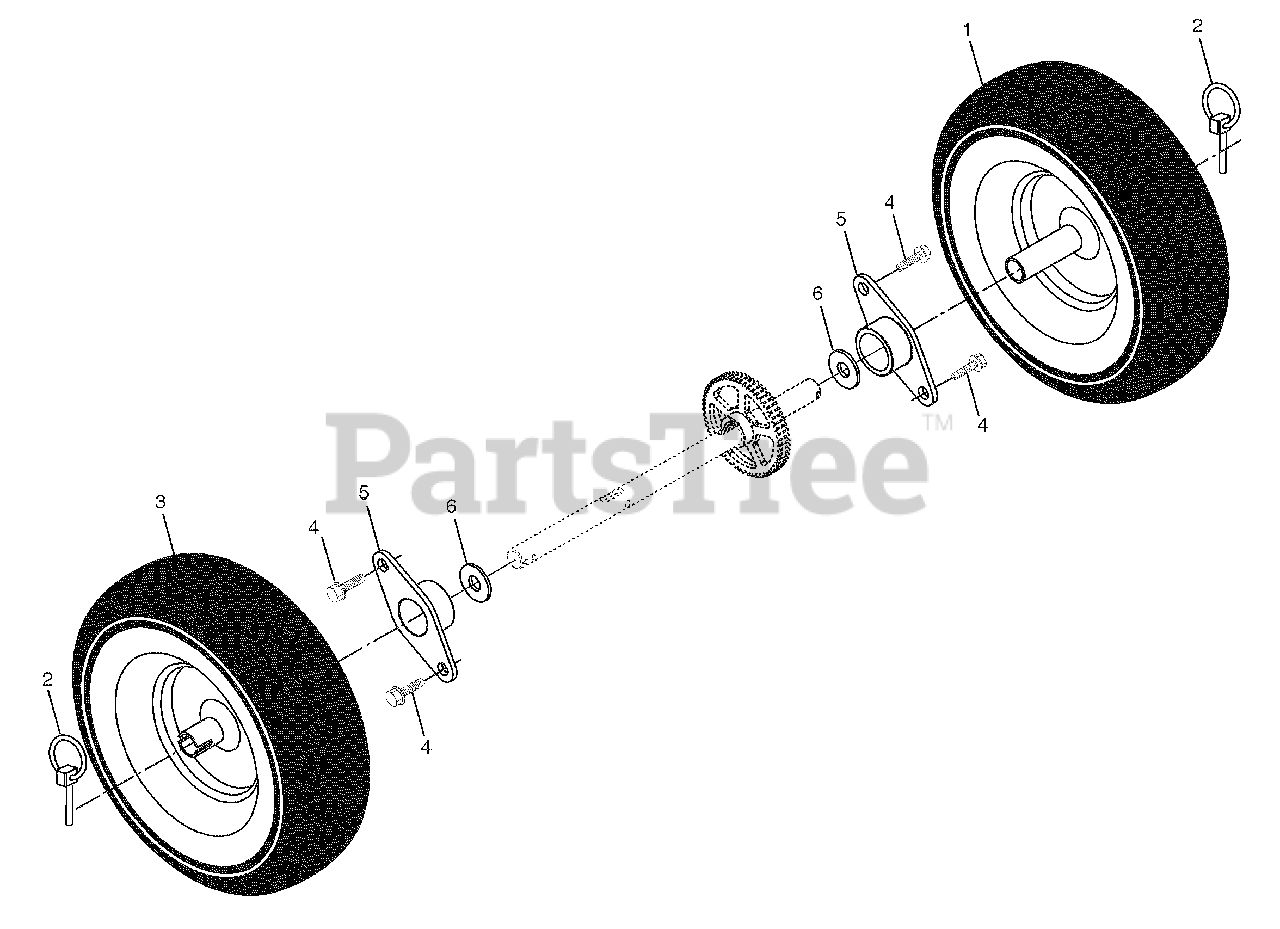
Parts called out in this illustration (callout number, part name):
1	Wheel Assembly, 13", LH
2	Pin, Klik 1/4
3	Wheel Assembly, 13", RH
4	Screw, Hex Head 5/16-18 x 5/8
5	Bearing, Axle
6	Washer, Thrust (1")
